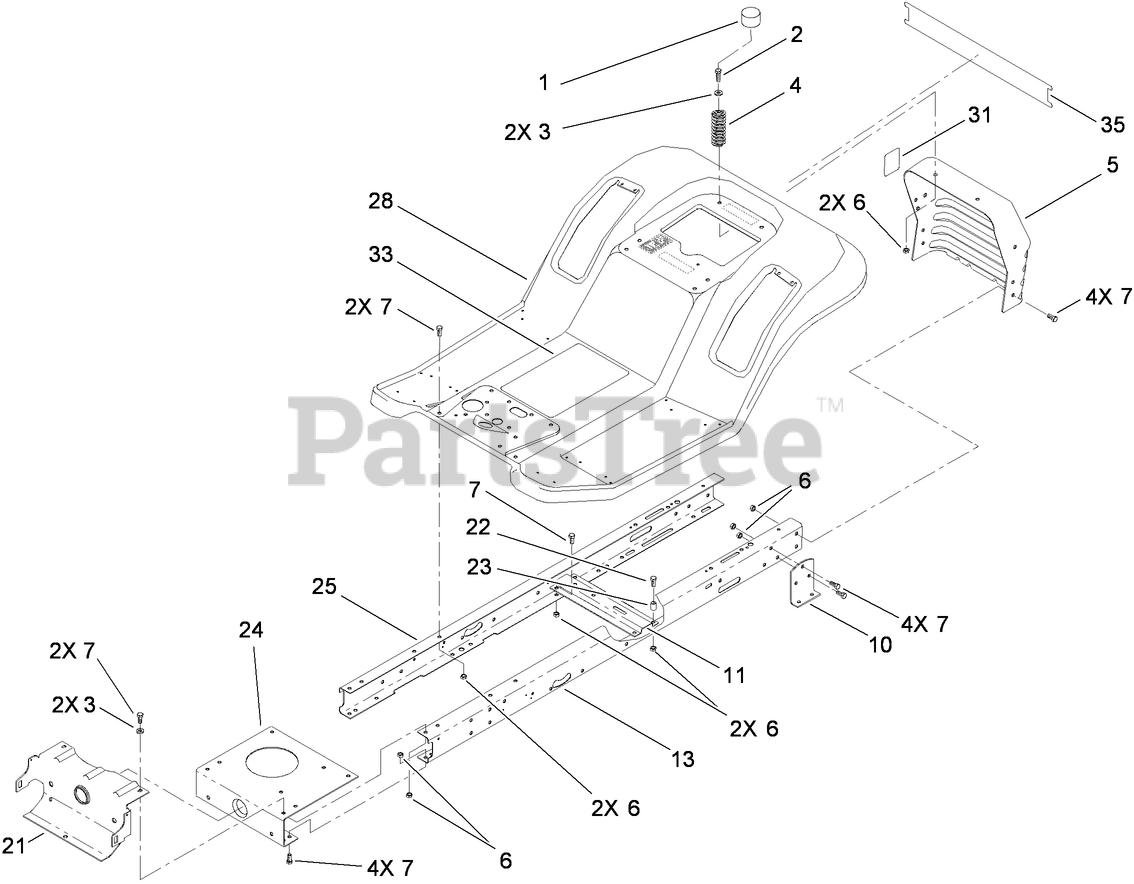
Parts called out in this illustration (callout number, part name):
1	CAP-PROTECTOR
2	SCREW-HH
3	WASHER-PLAIN
4	SPRING-COMPRESSION
5	SUPPORT-SEAT/REAR HITCH
6	NUT-LOCK, NI
7	SCREW-HH
10	BRACKET-TRANSAXLE, MOUNTING
11	BRACKET-IDLER PIVOT
13	RAIL-FRAME, LH
21	SUPPORT-AXLE, FRONT
22	SCREW-HH
23	SPACER
24	PLATE-MOUNTING, ENGINE
25	RAIL-FRAME, RH
28	REAR BODY ASM
31	DECAL-VALVE, DUMP
33	DECAL-INSTRUCTION, SAFETY
35	DECAL-REAR FENDER, LAWN TRACTORS
